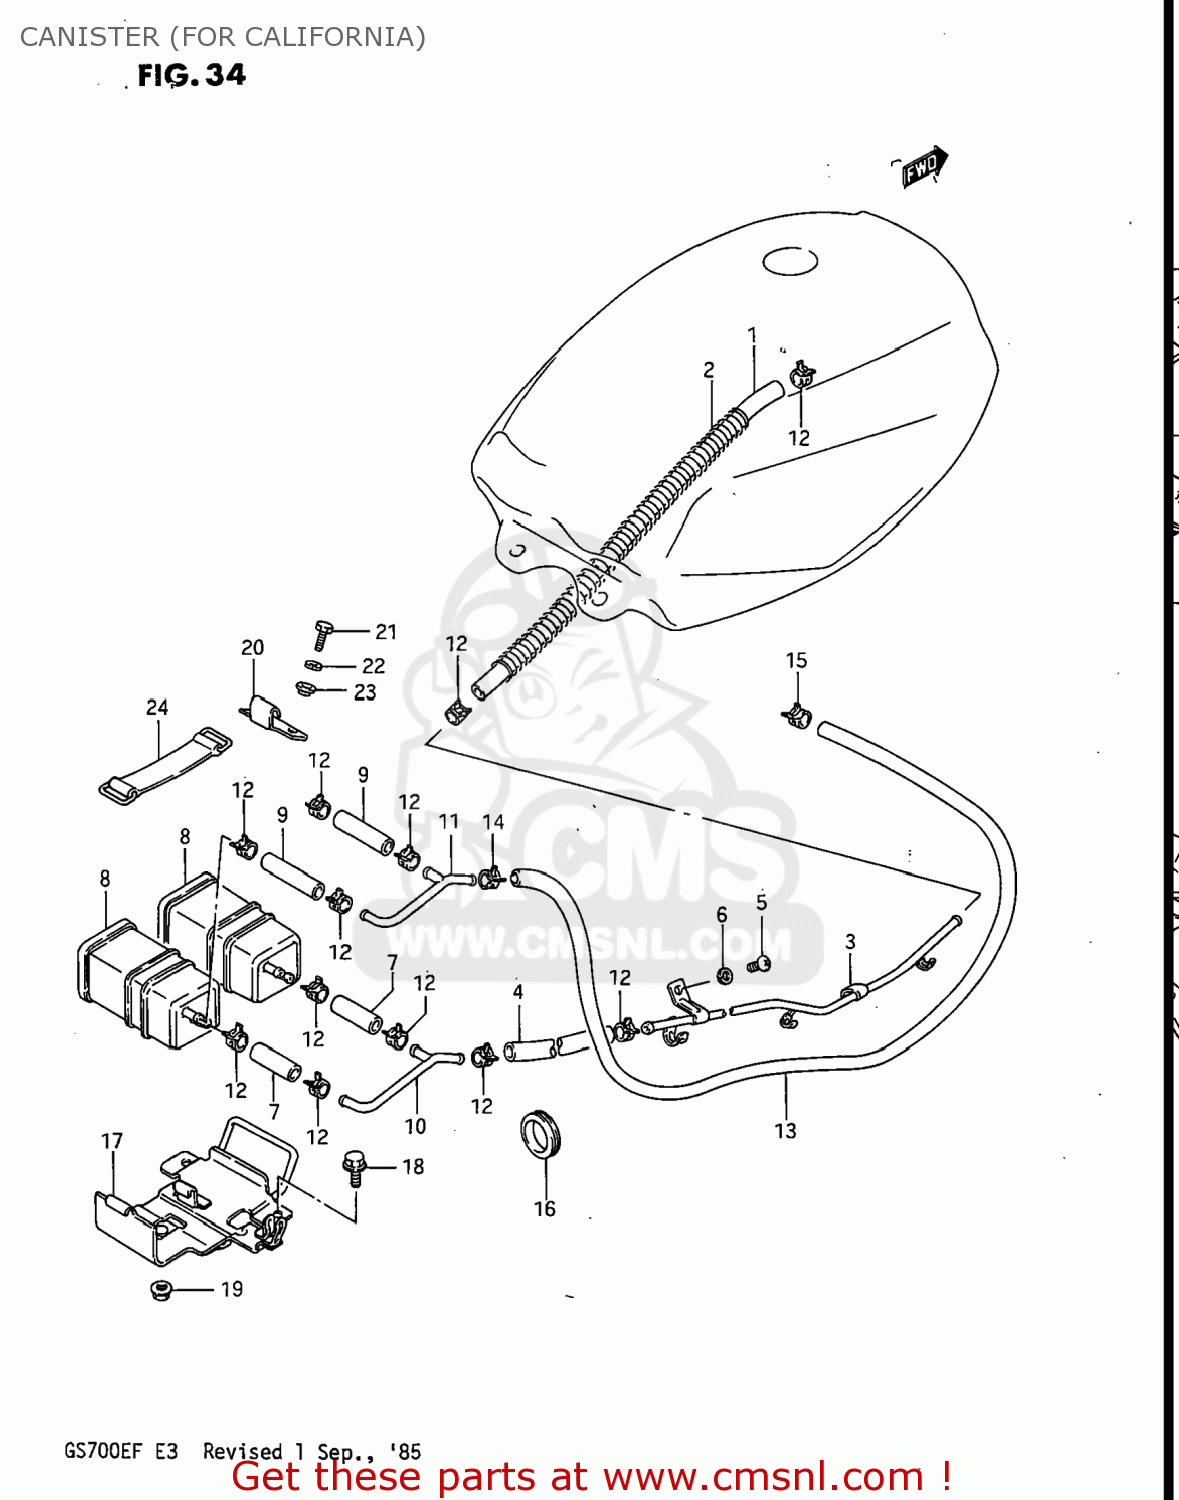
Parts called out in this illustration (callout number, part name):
1	HOSE
2	(CA) SPRING
3	PIPE
4	HOSE
5	SCREW
6	WASHER,LOCK
7	HOSE
8	(CA) CANISTER ASSEMBLY
9	HOSE
11	PIPE CANISTER
12	CLIP
13	HOSE
14	CLIP
15	CLIP
16	GROMMET
17	BRACKET,CANISTER
18	BOLT
19	NUT 6MM
21	BOLT
22	WASHER,LOCK
23	WASHER
24	BAND
